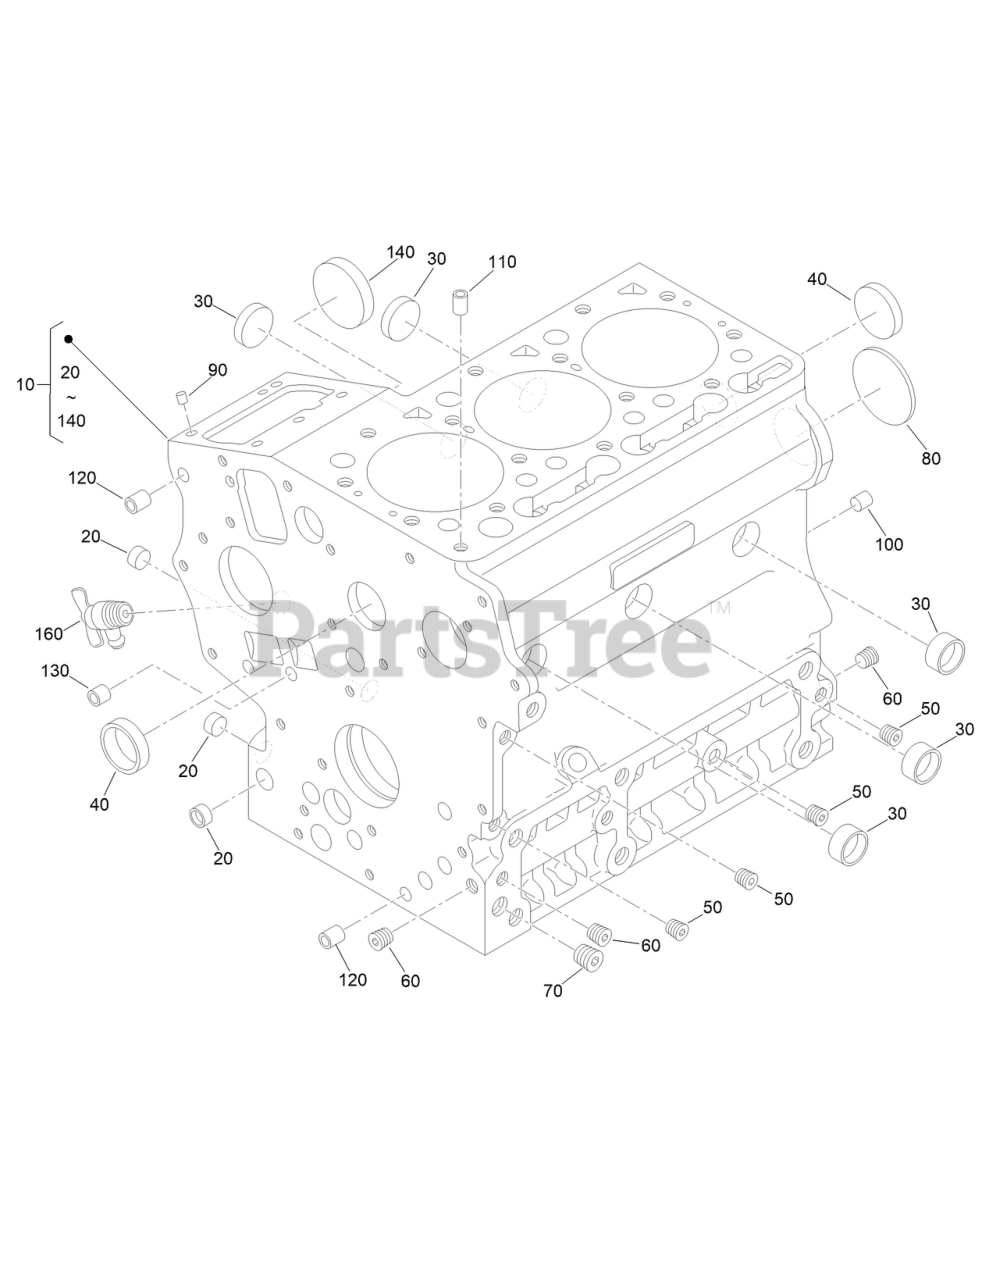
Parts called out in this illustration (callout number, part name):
10	CRANKCASE,COMP
20	CAP-SEALING
30	CAP-SEALING
40	CAP-SEALING
80	PLUG-EXPANSION
90	PIN-STRAIGHT
100	PIN-STRAIGHT
110	PIN-PIPE
120	PIN-PIPE
130	PIN-PIPE
140	COVER-FUEL, CAMSHAFT
160	DRAINCOCK ASM
